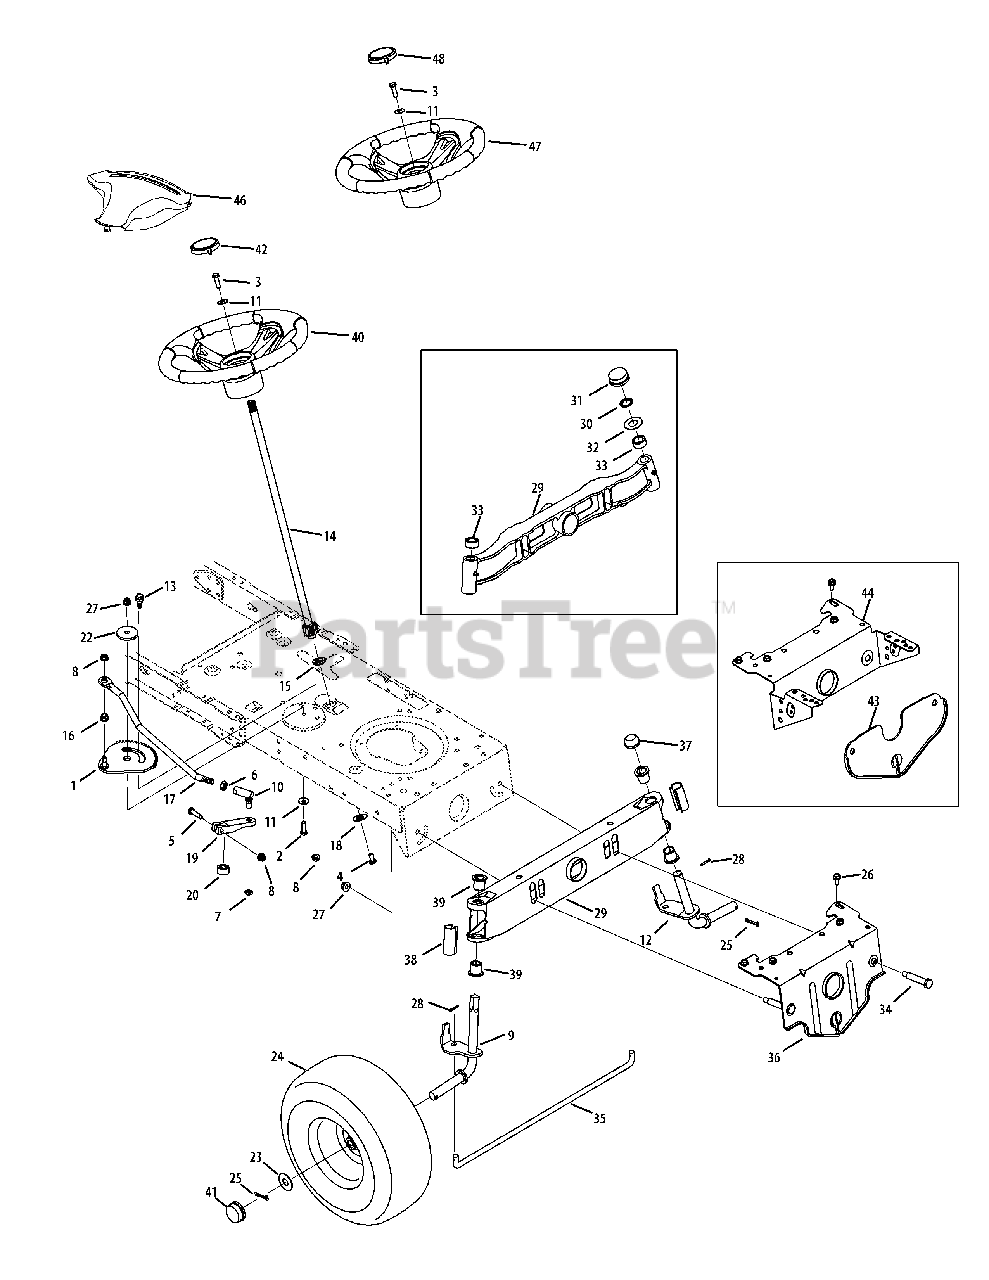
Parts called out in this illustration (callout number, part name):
1	Steering Gear Assembly
2	Hex Hd. Cap Scr 3/8-16 x 1,00 Gr. 5
3	Hex Screw 5/16-18 x 1.00 Special
4	Machine Screw 5/16-18 x .75
5	Hex Screw 5/16-18 x 1.75" Lg.
6	Hex Jam Nut 7/16-20
7	Hex Cent-L Nut 3/8-24 Gr. B
8	Flange Locknut 5/16-18 Gr. F, Nylon
9	Axle Assembly, RH
10	Ball Joint, 7/16 - 20
11	Cupped Washer .345 ID x .88 OD x .060
12	Axle Assembly, LH
13	Shoulder Screw .435 x .3485, 5/16-18
14	Steering Shaft, 5/8 Spline x 21.86
15	Hex Flange Bearing 5/8
16	Plastic Bushing .375 ID x .5
17	Steering Drag Link
18	Cap, 1.25 x .16
19	Steering Block
20	Spacer .710 ID x .125 OD x .56
22	Shoulder Spacer
23	Flat Washer .781 ID x 1.59 OD Special
24	Wheel Ass’y Complete 15 x 6 x 6
24	Tire Only
24	Air Valve
25	Cotter Pin 5/32 x 1.25
26	S-Tapp Scr 5/16-18 x .75
27	Flange Lock-Nut 3/8-16 Gr. F, Nylon
28	Cotter Pin 1/8" Dia x .75
29	Pivot Bar
29	Pivot Bar (cast)
30	Push Nut 3/4"
31	Axle End Cap
32	Flat Washer .78 x 1.59 x .060
33	Spacer .71 x .125 x .56
34	Shoulder Screw .500 x 2.380, 3/8-16
35	Tie Rod
36	Pivot Bar Bracket
37	Push Cap, .750
38	Axle End Cap, Standard
39	Flange Bearing .760 ID x .937 OD
40	Steering Wheel, Standard Grip, 3 spoke
41	Plastic Hub Cap
42	Steering Wheel Cap (w/o logo)
42	Steering Wheel Cap (sprig logo)
43	Front Deck Hanger Bracket
44	Pivot Bracket
46	Steering Wheel Cover
47	Steering Wheel, 4 spoke
48	Steering Cap
